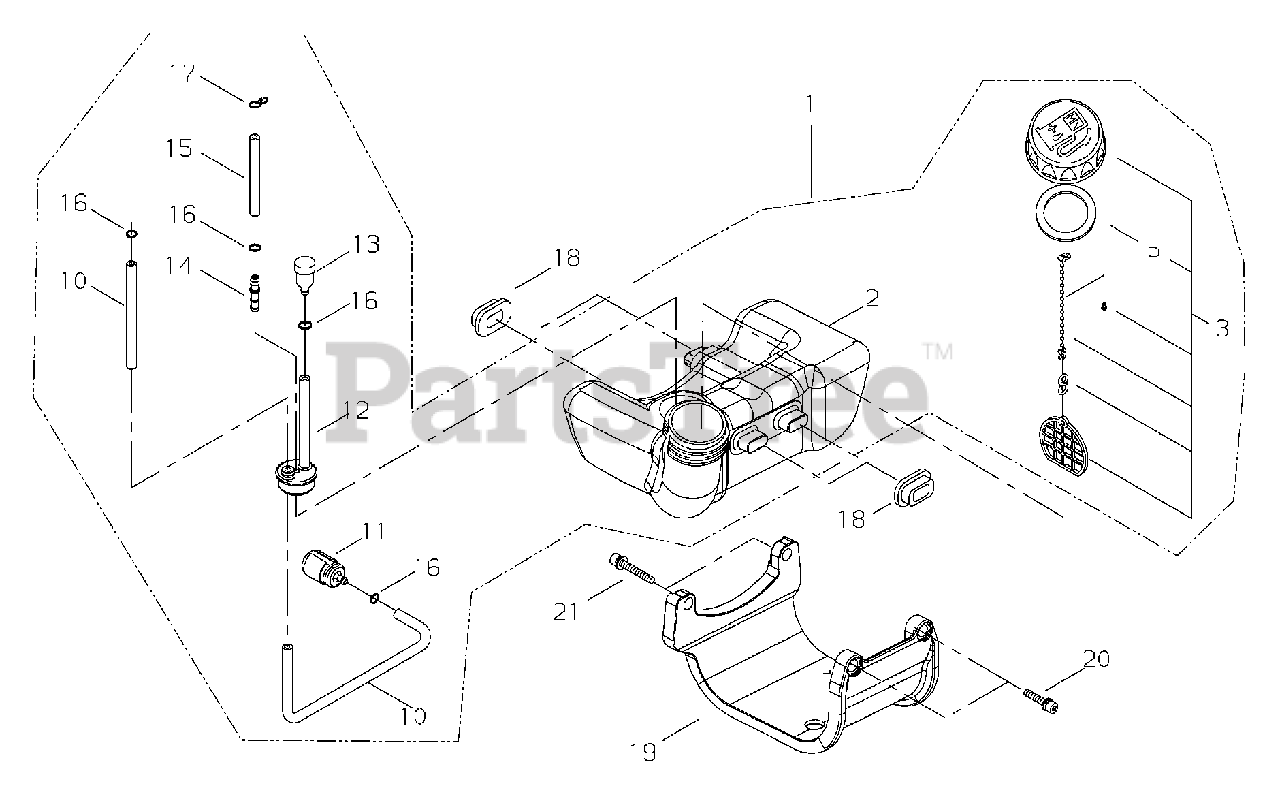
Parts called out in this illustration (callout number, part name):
1	FUEL TANK ASSY
2	TANK, FUEL
3	CAP ASSY, FUEL
5	GASKET, FUEL CAP
10	PIPE, FUEL 3.3×6×215
11	FILTER, FUEL 125-528
12	GROMMET, FUEL W/VENT PIPE
13	VENT ASSY
14	CONNECTOR, PIPE
15	PIPE, FUEL RETURN
16	CLIP Ø6
17	CLIP, SPRING Ø5.2
18	CUSHION, FUEL TANK
19	GUARD, FUEL TANK
20	BOLT M5×20
21	BOLT M5×40
